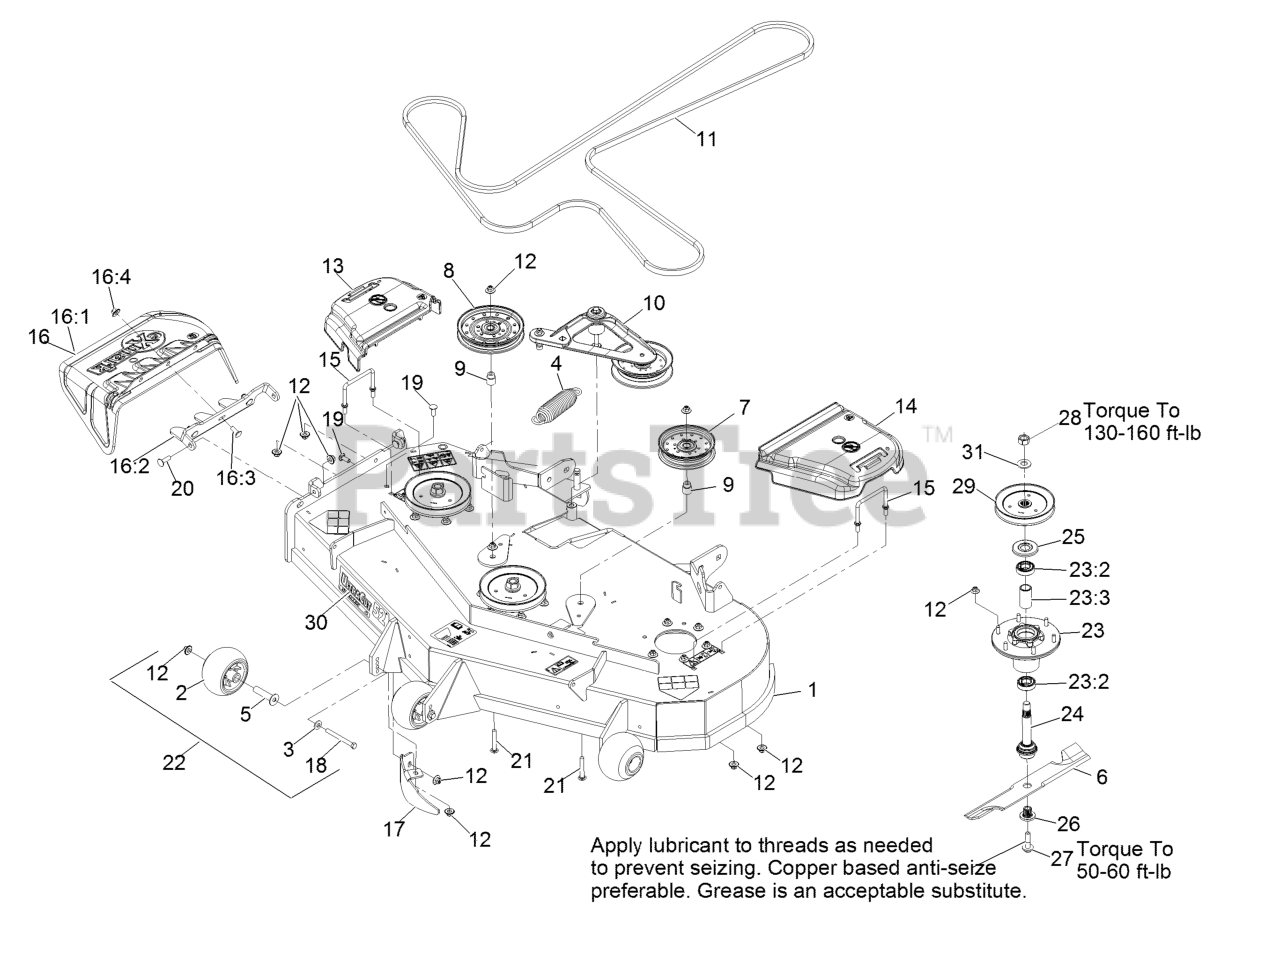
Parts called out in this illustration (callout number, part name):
1	ASM,DECK W/ DECALS 52
2	ROLLER-SCALP, ANTI
3	WASHER-BELLEVILLE
4	SPRING-EXTENSION
5	AXLE, ROLLER
9	BUSHING-IDLER
10	DECK IDLER ASM
11	BELT,V-B X 186.00"
12	Nut-Nyloc 3/8-16 Flg
13	COVER-BELT, RH
14	COVER-BELT, LH
15	WIREFORM-COVER
16	ASM,DISCHARGE CHUTE
16:1	CHUTE,DISCHARGE
16:2	BRACKET,DISCHARGE CHUTE
16:3	SCREW-CARR
16:4	Nut-Nyloc 3/8-16 Flg
17	BAFFLE-DOGLEG, LZ-VT52
18	SCREW-HH 3/8-16 X 3 3/4 GR 8
19	SCREW-CARR
20	Bolt-Carriage 3/8-16 X 1 1/4
21	SCREW-CARR
22	KIT, ANTI-SCALP ROLLER
23	ASM-CUTTER HSG WITH BEARINGS
23:2	BEARING-BALL
23:3	SPACER-BEARING
24	ASM-SPINDLE AND SEAL
25	GUARD,BEARING TOP .989
26	BUSHING,SPLINED
27	SCREW,SEMS 1/2-20 X 2.19
28	NUT-HEX
29	SHEAVE,BLADE DRIVE 6.50
30	DECAL,ULTRACUT 52 SERIES
